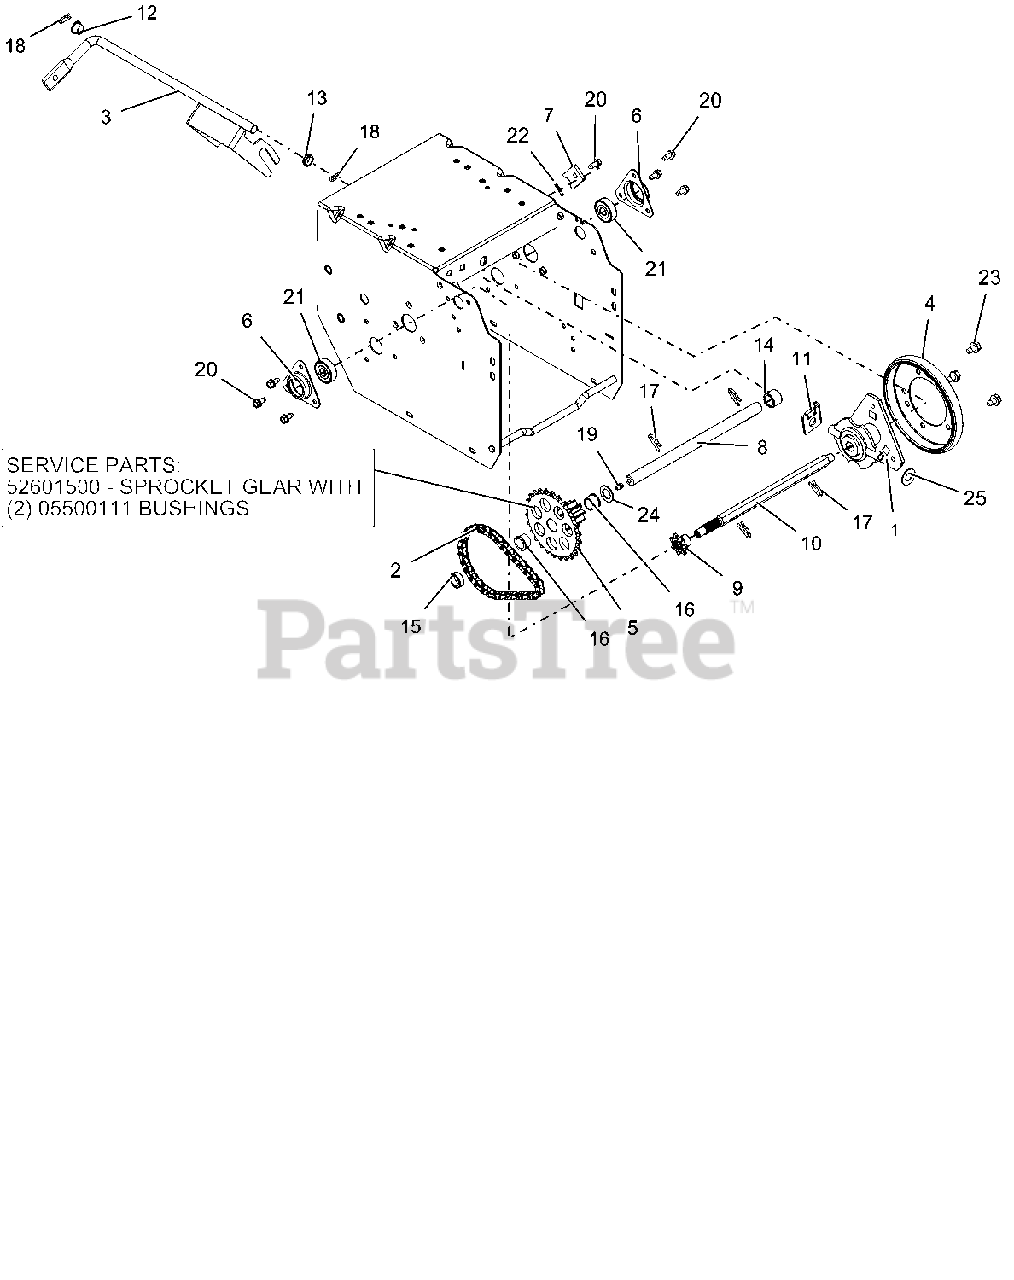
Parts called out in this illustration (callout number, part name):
1	CARRIER, DRIVE DISK
2	CHAIN - #41, 32 PITCHES
3	WELDMENT, SHIFT FORK
4	FRICTION, DISC
5	BSHG-FLG .625X.750X.500X.875
5	PINION & SPROCKET
5	PINION & SPROCKET W/BUSHINGS
6	FLANGE, BEARING
7	TAB, ANTI ROTATION
8	SHAFT, PINION
9	SPROCKET, PINION 7T W/SPLINE
10	SHAFT, HEX W/SPLINE
11	BRACKET, FORMED - SHIFT FORK
12	BUSHING, POLYLINER-.50 SPLIT
13	BUSHING, POLYLINER-.50 SNAPIN
14	SPACER, .635X.880X.611
15	BSHG-SLV, .635X.880X.305
16	BSHG-FLG .625X.750X.500X.875
17	PIN, SPRING CLIP
18	CLIP, SPRING
19	ZERK,FITTING .25X.125 DRIVE IN
20	SCR-TAP .25-20X.50 HWH TR YWZ
21	BRG-BALL .437X1.375X.437
22	@PIN-GRV .125X1.00 TP E ALLOY
23	@SCR-TAP .31-18X.50 HWH TR YWZ
24	WSHR-FL-STL .630X1.005X.062 YZ
25	WSHR-FL-STL .505X1.00X.062YWZC
